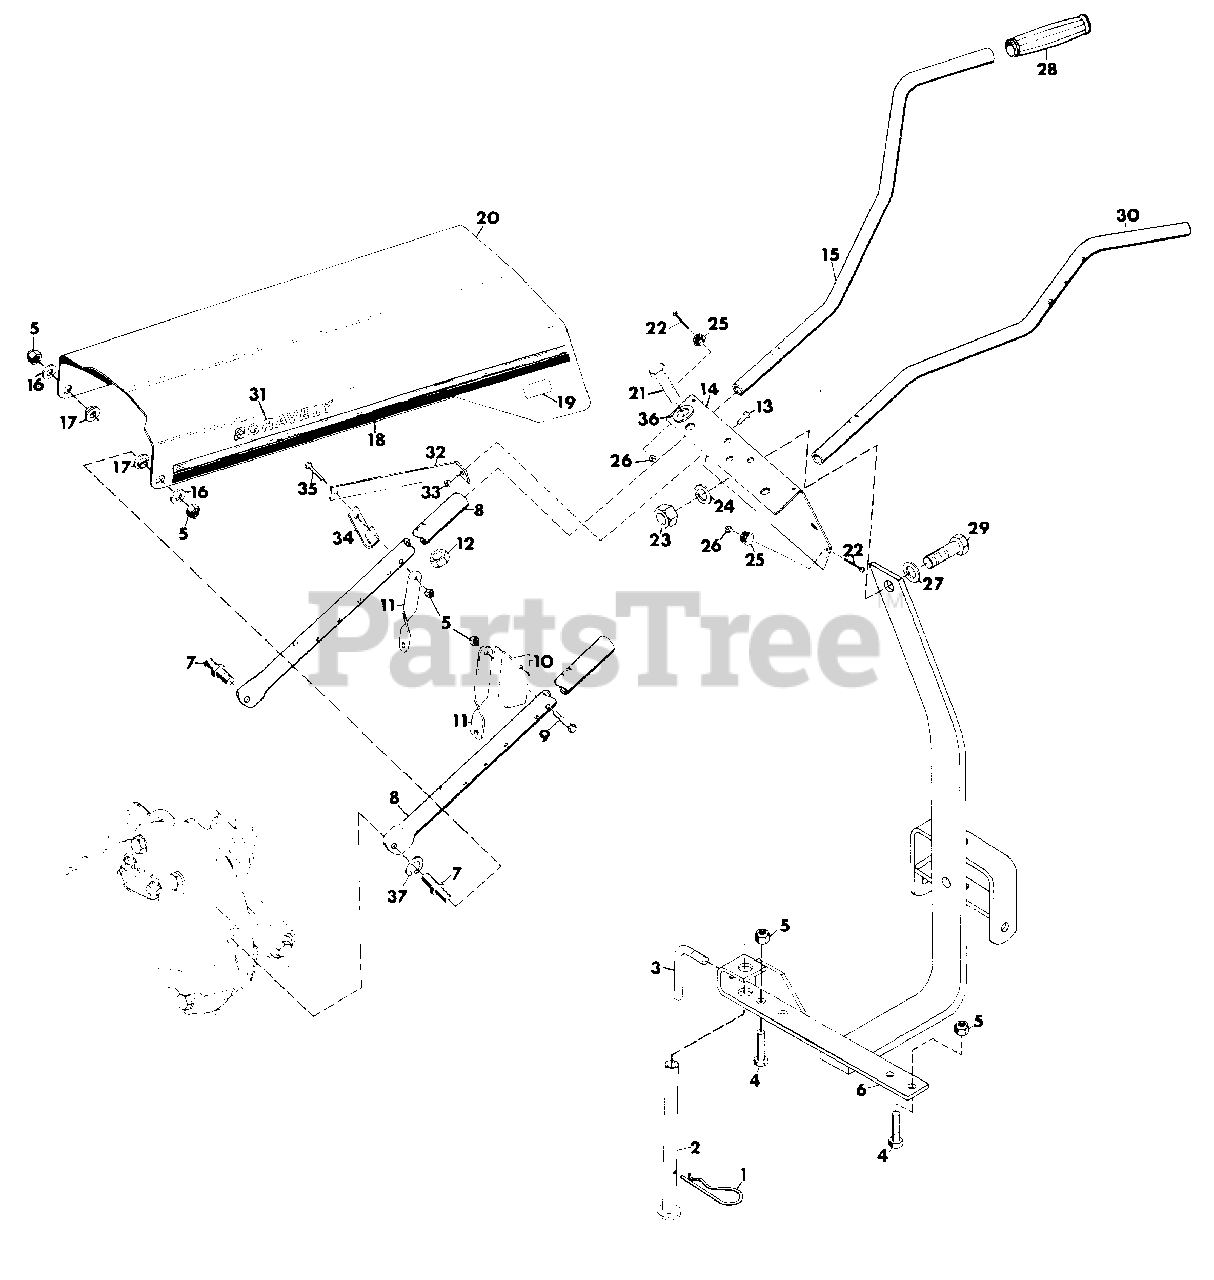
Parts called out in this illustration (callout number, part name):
1	COTTER, HAIR PIN
2	KICK STAND
3	HANDLE, ADJUSTING
4	BOLT, HEX 3/8-16X1.50
5	NUT, LOCK 3/8-16
6	HITCH, WELDMENT 8 H.P.
7	STUD, HOOD
8	SUPPORT, TUBE
9	BOLT, HEX 3/8-16X2.25
10	STOP, ROD
11	BRACE, HANDLE
12	NUT, HEX 1/2-20
13	BOLT, HEX 1/4-20X.625(MODEL 5240)
14	PANEL, INSTRUMENT MANUAL START
15	BAR, RIGHT HANDLE
16	WASHER, FLAT .406X.812X.065
17	BUSHING
18	STRIPE, SIDE
19	DECAL, MODEL 5200
19	DECAL, MODEL 5240
20	HOOD
21	BOLT, HEX 1/2-20X2
22	SCREW, MACH. 6-32X5/8 HD C-RECESS
23	NUT, HEX 5/8-11
24	WASHER, LOCK 5/8 SP
25	BUMPER
26	NUT, MACH. LOCK 6-32
27	WASHER, FLAT .656X1.250X.100
28	GRIP, HAND
29	BOLT, HEX 5/8-11X1.50
30	BAR, LEFT HANDLE
31	DECAL, GRAVELY LOGO
32	BRACE, INSTRUMENT PANEL(MODEL 5240)
33	NUT, LOCK 1/4-20(MODEL 5240)
34	RETAINER, 2-SPEED CONTROL(MODEL 5240)
35	BOLT, HEX 3/8-16X2.50
36	WASHER, FLAT .531X1.062X.095
37	WASHER, LOCK 3/8 REG.
NS	DECAL, AMERICA
